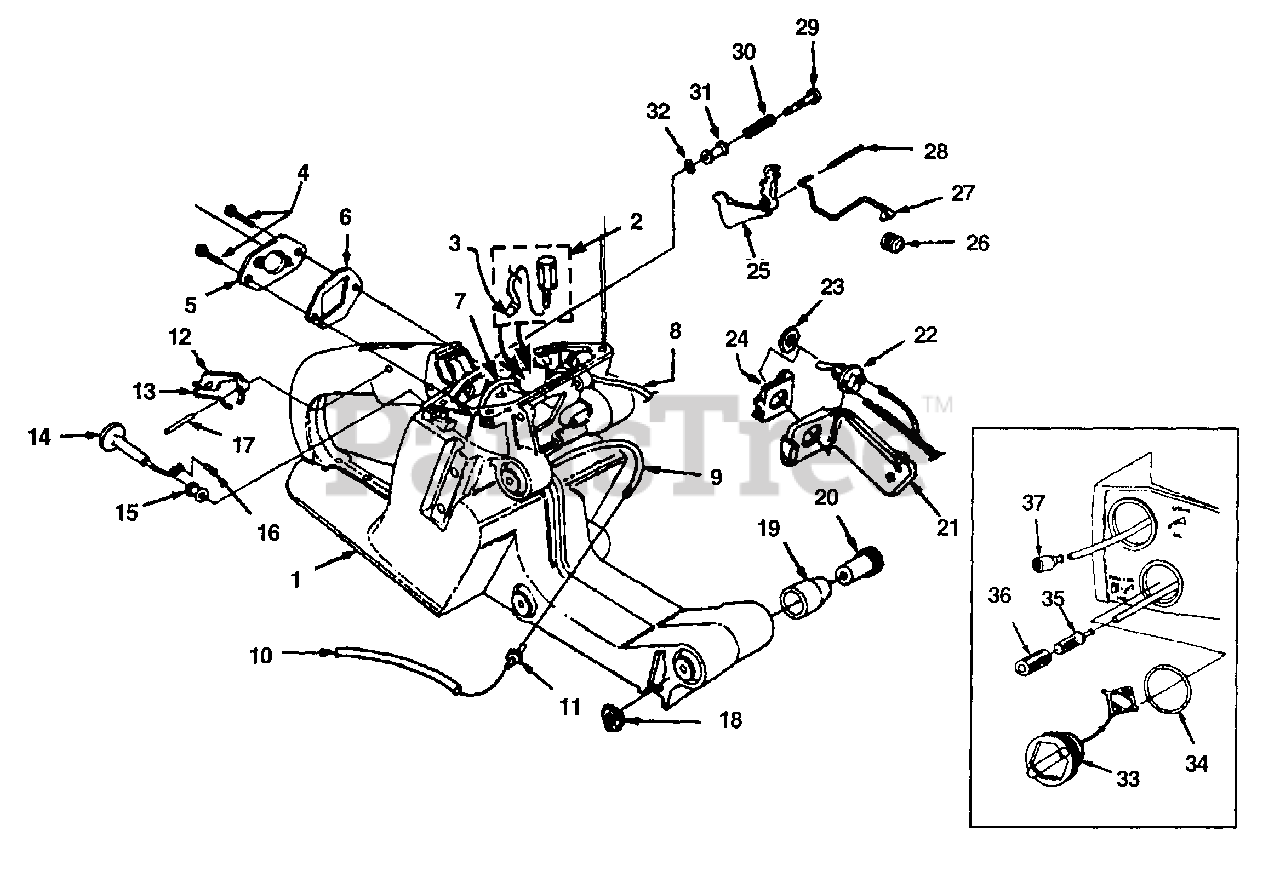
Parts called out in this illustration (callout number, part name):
1	HOUSING - Engine
2	TANK VENT KIT
3	VALVE - Duck Bill
4	SCREW - Torx Truss (10-24 X 1/2")
5	ADAPTOR - Carburetor
6	GASKET - Carburetor
7	TUBING - Rubber (Fuel Line, 9 1/2")
8	TUBING - Rubber (Oil Line, 5")
9	TUBING - Rubber (Pulse Line, 6 1/2")
10	TUBING - Rubber (5 3/4")
11	FITTING - Inline Fuel
12	TRIGGER - Lock
13	SPRING - Flat
14	ROD - Choke
15	GROMMET
16	PIN - Cotter
17	PIN - Trigger
18	Nut - Locking Hex (10-32)
19	ISOLATOR - Vibration
20	SLEEVE - Flanged
21	COVER
22	SWITCH - Toggle
23	NUT - Hex
24	PLATE - Indicating
25	TRIGGER - Throttle
26	BOOT - Throttle Rod
27	ROD - Throttle
28	PIN - Trigger
29	PIN - Throttle Lock
30	SPRING - Compression
31	BUSHING - Flanged
32	RING - Retaining
33	CAP - Fuel & Oil
34	GASKET - Fuel & Oil Cap
35	FILTER - Fuel
36	ELEMENT - Felt Filter
37	OIL FILTER
